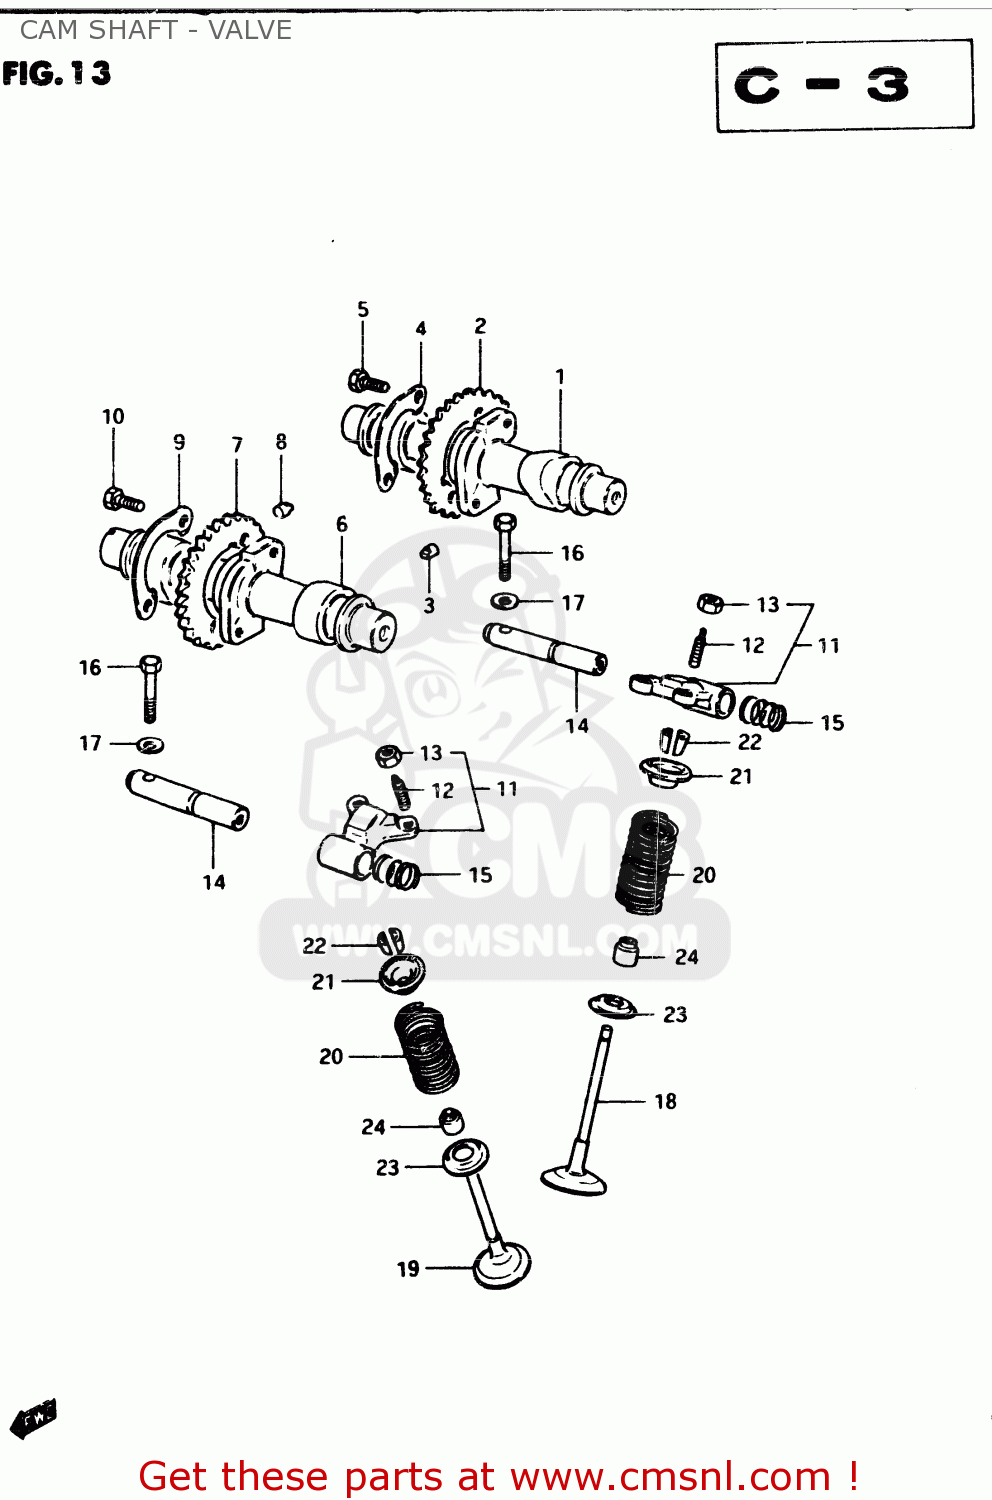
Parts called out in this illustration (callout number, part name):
1	CAMSHAFT
2	SPROCKET,INTAKE CAMSHAFT
3	PIN,SPROCKET
4	WASHER,CAM CHAIN SPROCKET
5	BOLT(6X12.5)
6	CAMSHAFT,EXHAUST
7	SPROCKET,EXHAUST CAMSHAFT
8	PIN,SPROCKET
9	WASHER,CAM CHAIN SPROCKET
10	BOLT(6X12.5)
11	ARM,VALVE ROCKER
12	SCREW,TAPPET ADJUSTING
13	NUT,ADJUSTING
14	SHAFT,VALVE ROCKER ARM
15	SPRING
16	BOLT
17	WASHER
18	VALVE,INTAKE
19	VALVE,EXHAUST
20	SPRING,VALVE
21	RETAINER,VALVE SPRING
22	COTTER VALVE
23	SEAT,VALVE SPRING
24	OIL SEAL
